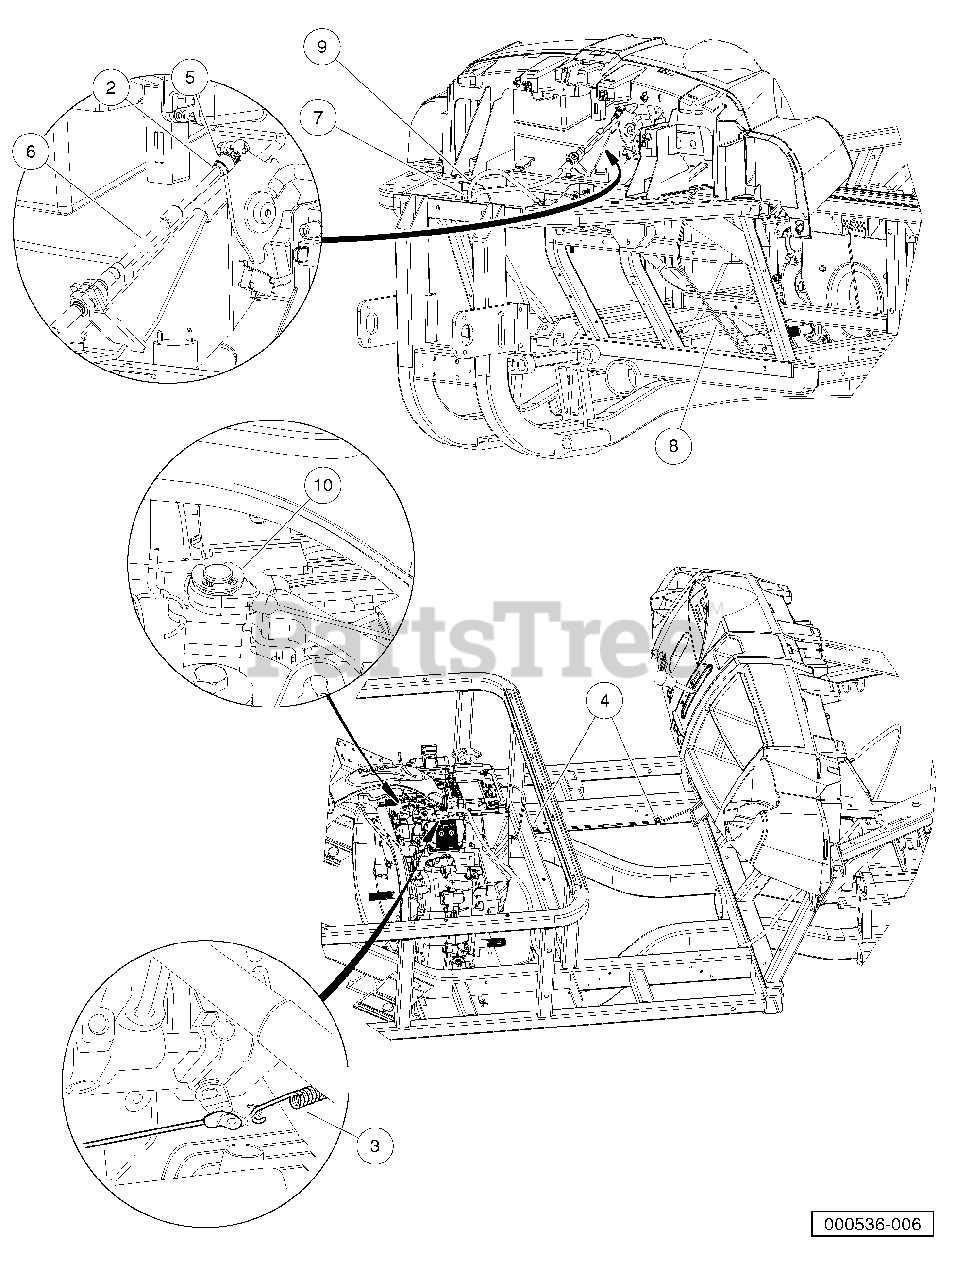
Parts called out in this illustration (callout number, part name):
1	Instl, Cables, Gas, Se, Fh680d
2	Nut, 1/4-28 Hex Jam
4	Clip, Brake Line
5	Joint, Ball, .346 Dia
6	Cable, Trans Shift, AWD, Long
7	Cable, Acc, Awd, G, Fh680d, Se
8	Cable, Choke, Awd, Fh680d, Se
9	Tie Wrap, 8" Nylon
10	Ring, Retaining
